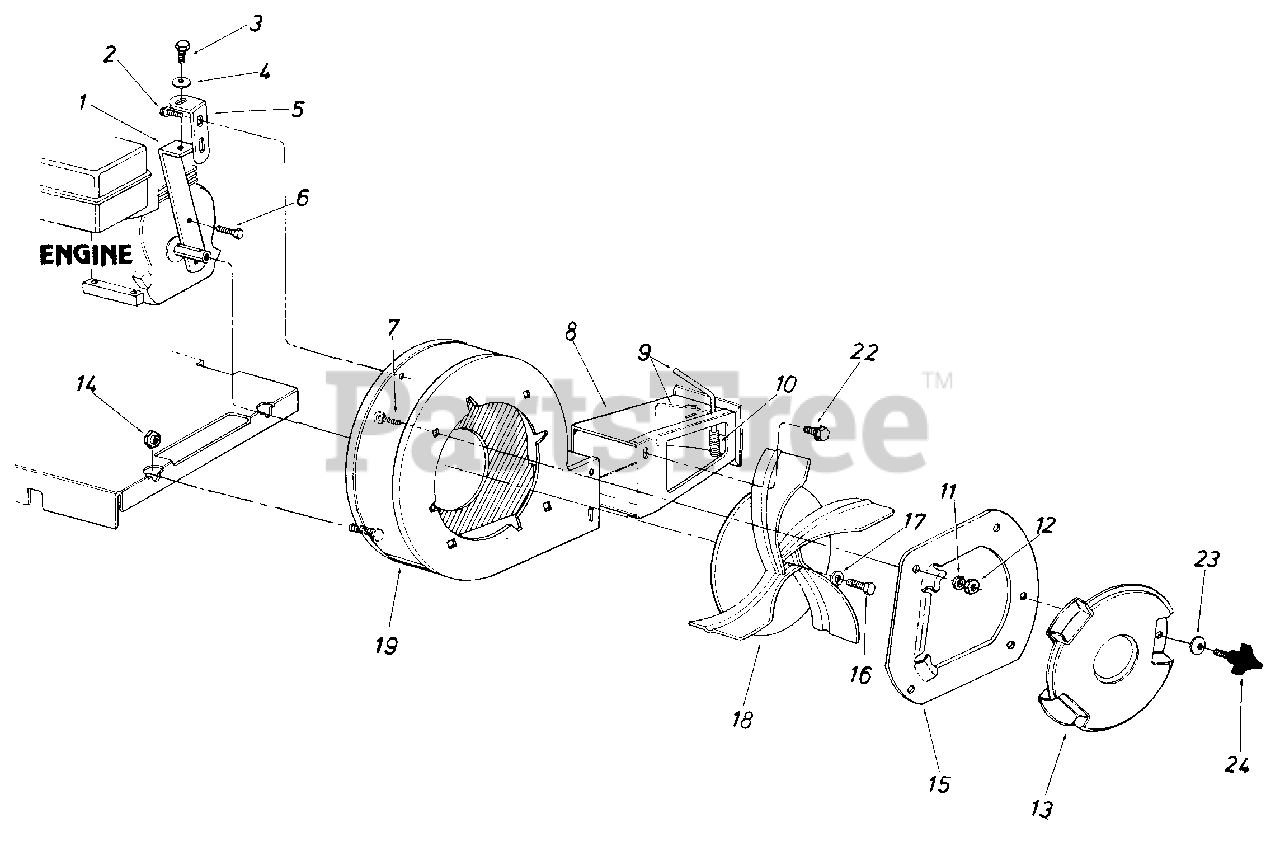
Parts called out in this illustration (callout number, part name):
3	Hex Bolt 5/16-18 x .75" Lg.*
4	L.-Wash.5/16" I.D.*
7	Carriage Bolt 5/16-18 x .62" Lg. *
11	L.-Wash.5/16" I.D.*
12	Hex Nut 5/16-18 Thd.*
13	Blower Guard
14	Hex Shoulder Nut.50" I.D.
15	Nozzle Plate Ass'y.
16	Hex Bolt 3/8-24 x 1.25" Lg.*
17	L.-Wash. 3/8" I.D. HD.
18	Air Vane Plate Ass'y.
19	Blower Housing Ass'y.-Comp.
22	Hex Sems Bolt 5/16-18 x .62" Lg.*
23	Bel levil le Wash. 34" 1 .D. x .87"O.D.
24	3-Arm Thumb Scr. 5/16-18 x . 75" Lg.
